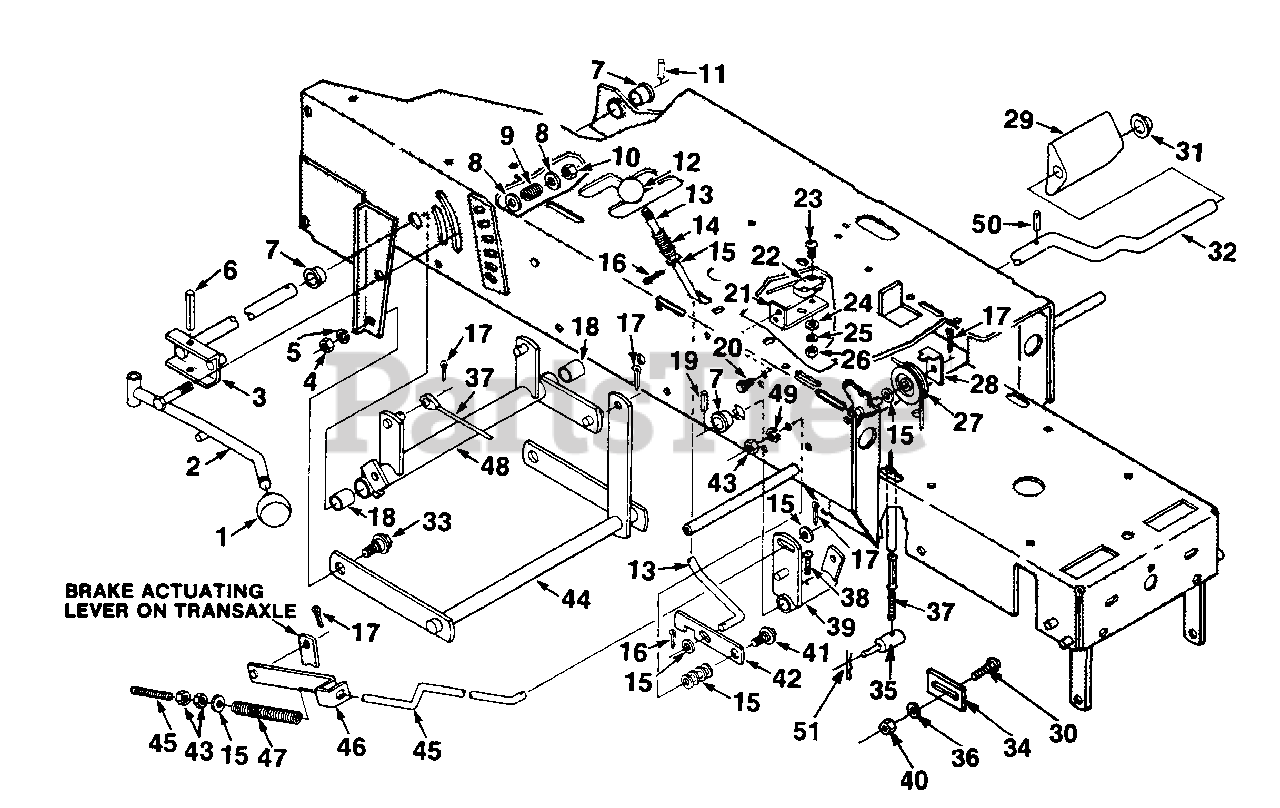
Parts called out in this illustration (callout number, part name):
1	KNOB- implement lift handle
2	HANDLE- Lift
3	LIFT HANDLE BRACKET & ROD
4	NUT- 3/8-16 hex
5	WASHER- Lock 3/8 hvy.
6	PIN- Groove 5/16 x 2 1/4
7	BUSHING- Flanged
8	WASHER- Flat 3/8
9	SPRING- Compression
10	NUT- 5/16-18 hex centerlock
11	PIN- 3/16 x 1
12	KNOB- Parking brake
13	ROD- Crack lock
14	SPRING- Compression
15	WASHER- Flat 11/13
16	PIN- Cotter 1/8 x 3/4
17	PIN- Cotter
18	BUSHING- Pivot
19	PIN- 3/16 x 1
20	BOLT- 1/4-14
21	BRACKET- Safety switch
22	SWITCH- Safety
23	SCREW #4-40 x 1.00 slotted truss hd
24	WASHER- flat
25	WASHER- Lock #4 Reg
26	NUT- #4-40 hex
27	PULLEY- Lift cable
28	RETAINER- Lift cable
29	PEDAL- Clutch
31	NUT- 5/8 push on
32	ROD- Clutch
33	BOLT- Shoulder
36	WASHER
37	CABLE- Deck lift
39	CLUTCH ROD ACTUATOR ASSY.
41	BOLT- Idler pivot
42	LATCH- Parking brake
43	NUT- 5/16-18 hex
44	REAR LIFT BAR ASSY.
45	ROD-Brake
46	BRAKE SPRING BRACKET ASSY.
47	SPRING- Brake compression
48	REAR LIFT & BUSHING ASSY.
49	WASHER- Lock 5/16 hvy
50	PIN- Roll
51	PIN- Hair
